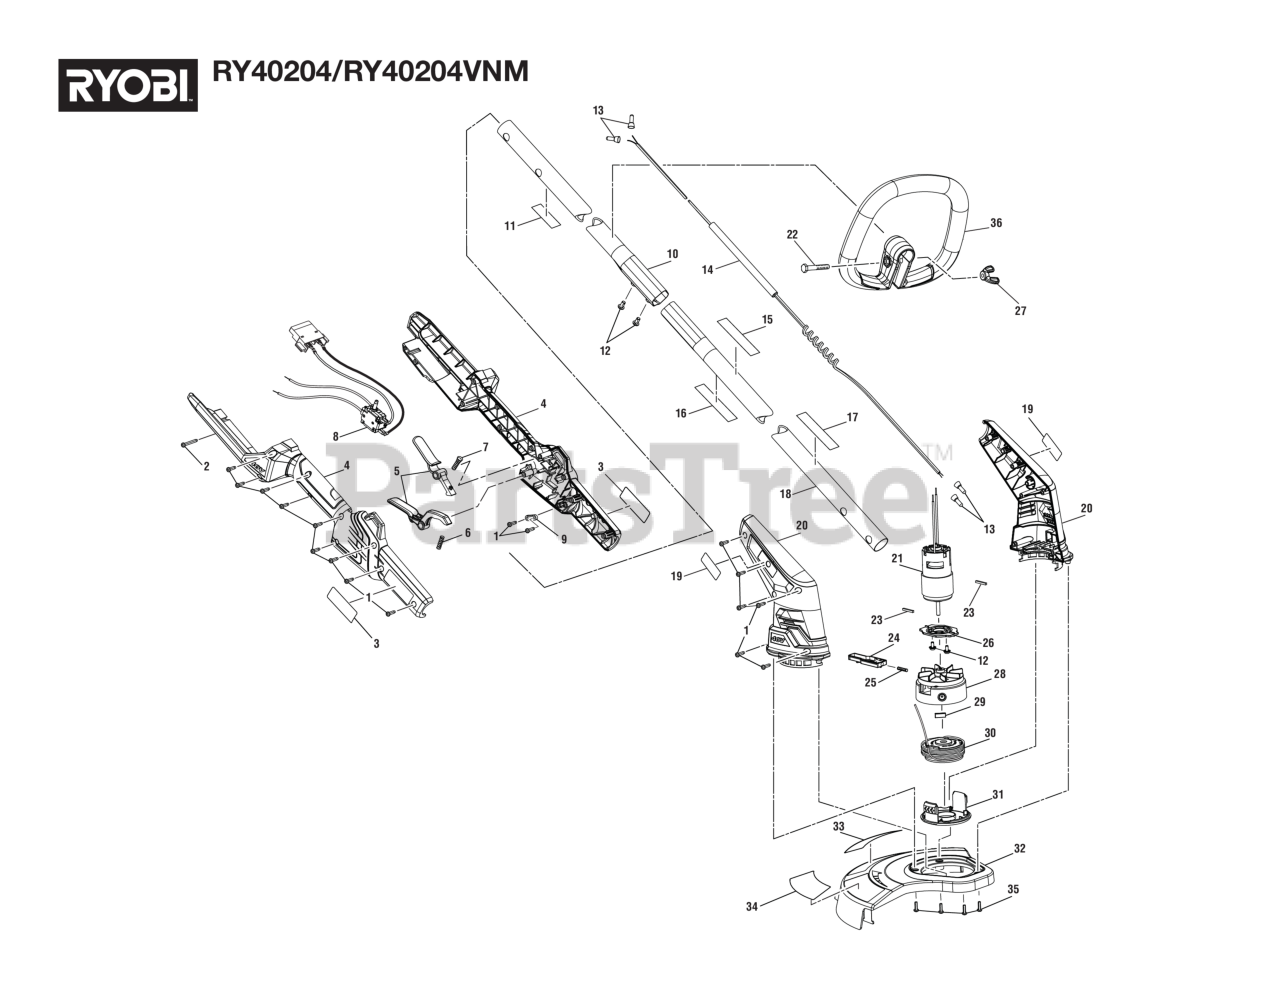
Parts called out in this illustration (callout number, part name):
1	Screw (M4 x 14 mm, T15 Torx Pan Hd.))
2	Screw (M4-18 x 30 mm, T15 Torx Soc. Hd.)
3	Logo Label
4	Handle Housing Assembly, ABS
5	Trigger Assembly, POM
6	Compression Spring (Trigger)
7	Compression Spring (Trigger)
8	Wiring Harness
9	Strain Relief Plate
10	Upper Tube Assy. (RY40204, Inc. Key No. 11)
11	Data Label (RY40204)
12	Screw w/Lock Washer (M5 x 8 mm, Pan Hd.)
13	Wire Connector (Closed End)
14	Spring Wire, 18 AWG 300V
15	Warning Icon Label
16	Warning Label (Upper End)
17	Label, Logo, Shaft
18	Lower Tube w/ Labels, Low Carbon Steel
19	Label, Logo, Motor Housing
20	Motor Housing Assy. (Inc. Key No. 19)
22	Bolt (1/4-20 x 45 mm, Cap Hex Hd.)
23	Rubber Plate (Motor Plate)
24	Slider Assembly
25	Compression Spring (Internal Tooth)
26	Mounting Plate
27	Wing Nut (1/4-20, Plastic)
28	Spool Base w/Fan
29	BALANCE PLATE
30	Spool w/ Line Assembly
31	Spool Cap (AC14HCA)
32	Guard Assembly, PP
33	Adjustable Cutting Width Label
34	Auto-Feed Label
35	Screw (M4 x 12 mm, Pan Hd.)
36	Front Handle
